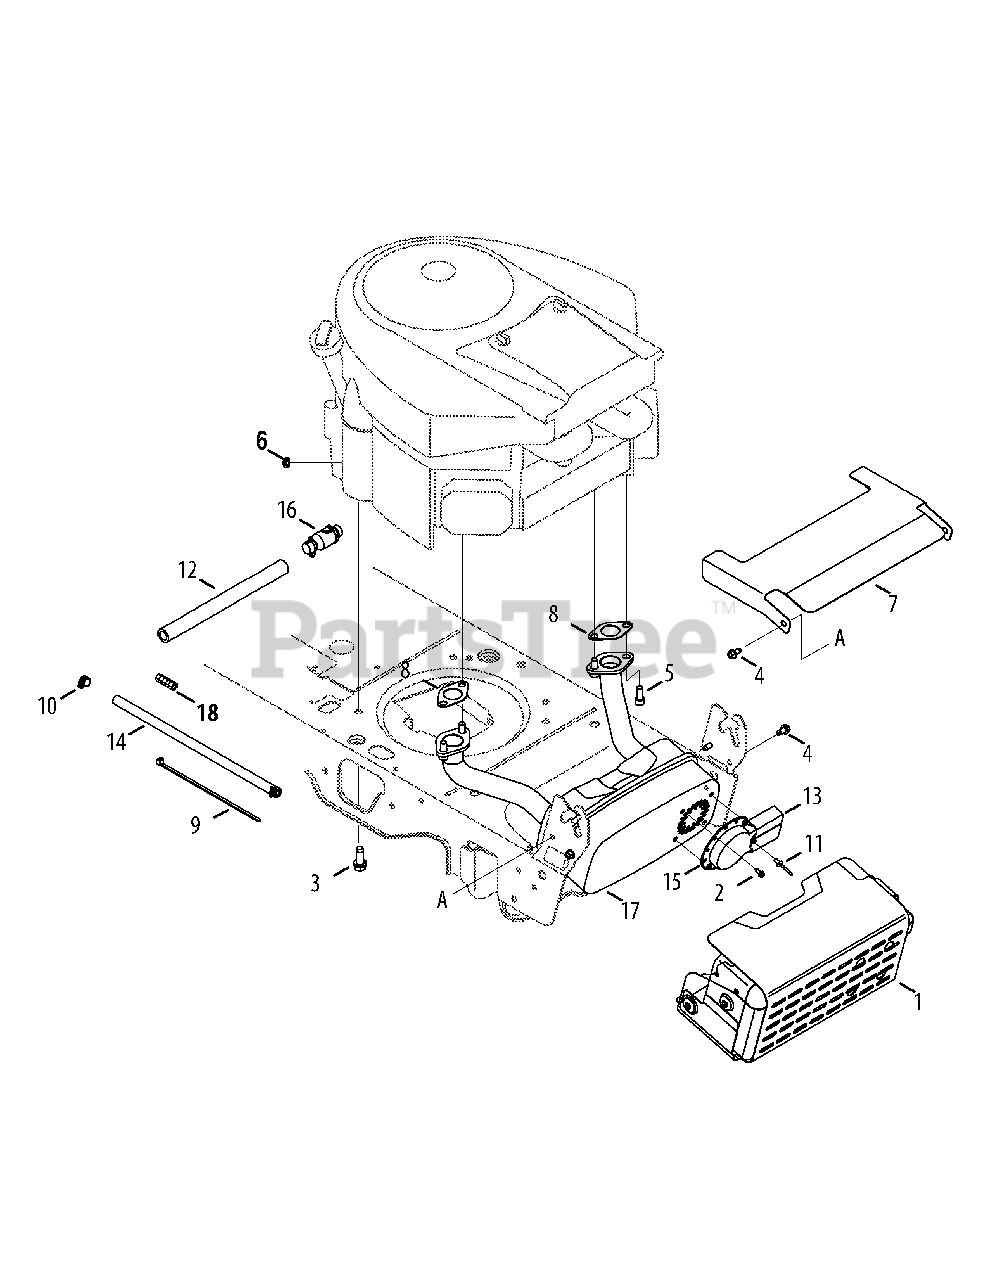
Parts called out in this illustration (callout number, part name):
1	Mulffler Shield Assembly
2	Screw, Indented Washer, #8-18x0.500
3	Taptite Screw, 3/8-16x1.000
4	Taptite Screw, 1/4-20x0.500
5	Socket Head Screw, 5/16-18x.750
6	Sems Nut, 1/4-20
7	Heat Shield
8	Exhaust Gasket
9	Cable Tie, 3/16 x .05 x 7.4
10	Hose Clamp, .490 DIA.
11	Rivet, .188 DIA x .300 L
12	Oil Drain Extension Hose
13	Muffler Deflector
14	Fuel Hose
15	Long Muffler Deflector, (EPA)
16	Oil Drain
17	Muffler
18	Hose Vent
